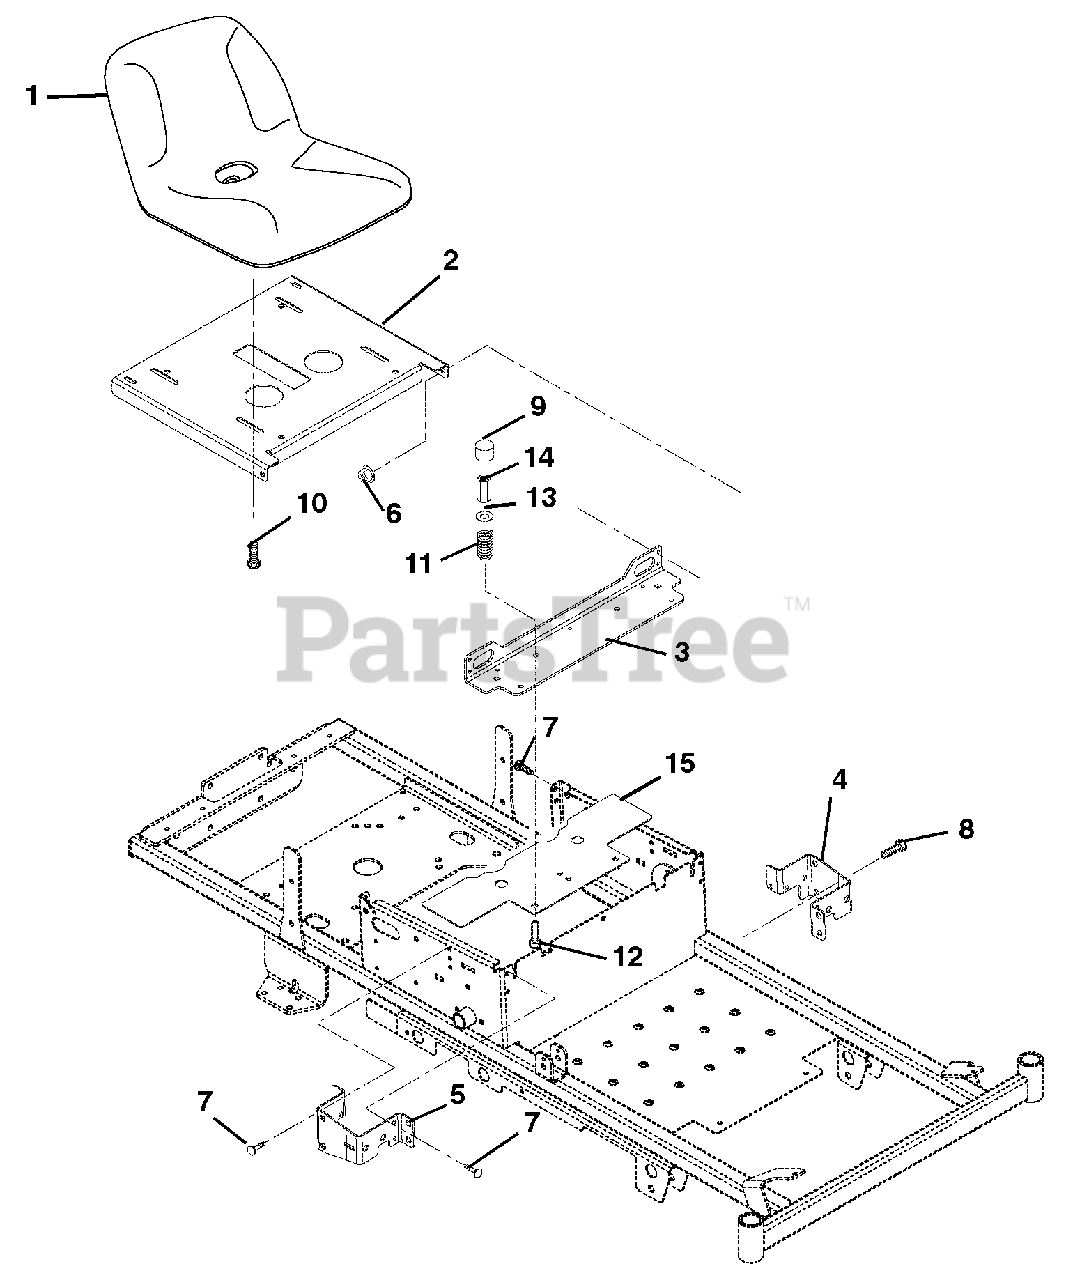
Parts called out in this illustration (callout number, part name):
1	SEAT, MILSCO XB150 GRAY
2	SEAT PLATE,
3	BRKT, SEAT SPRING
4	WDMT, RH STEERING STOP
5	WDMT, LH STEERING STOP
6	@NUT-LK-TOP-FLG .38-16 YWZC
7	@SCR-TAP .31-18X.50 HWH TR YWZ
8	BOLT-SHLDR .375-16X.150
9	HUB CAP
10	5/16-18X3/4 HX/W/HD WHIZ
11	SPRING, SEAT
12	@BLT-RDHDSQNK .31-18X1.50 G5YZ
13	WSHR-FL-STL .328X.87X.179 YWZC
14	NUT, COUPLING 5/16-18 X 1 3/4
15	GUARD, ZOOM FINGER
